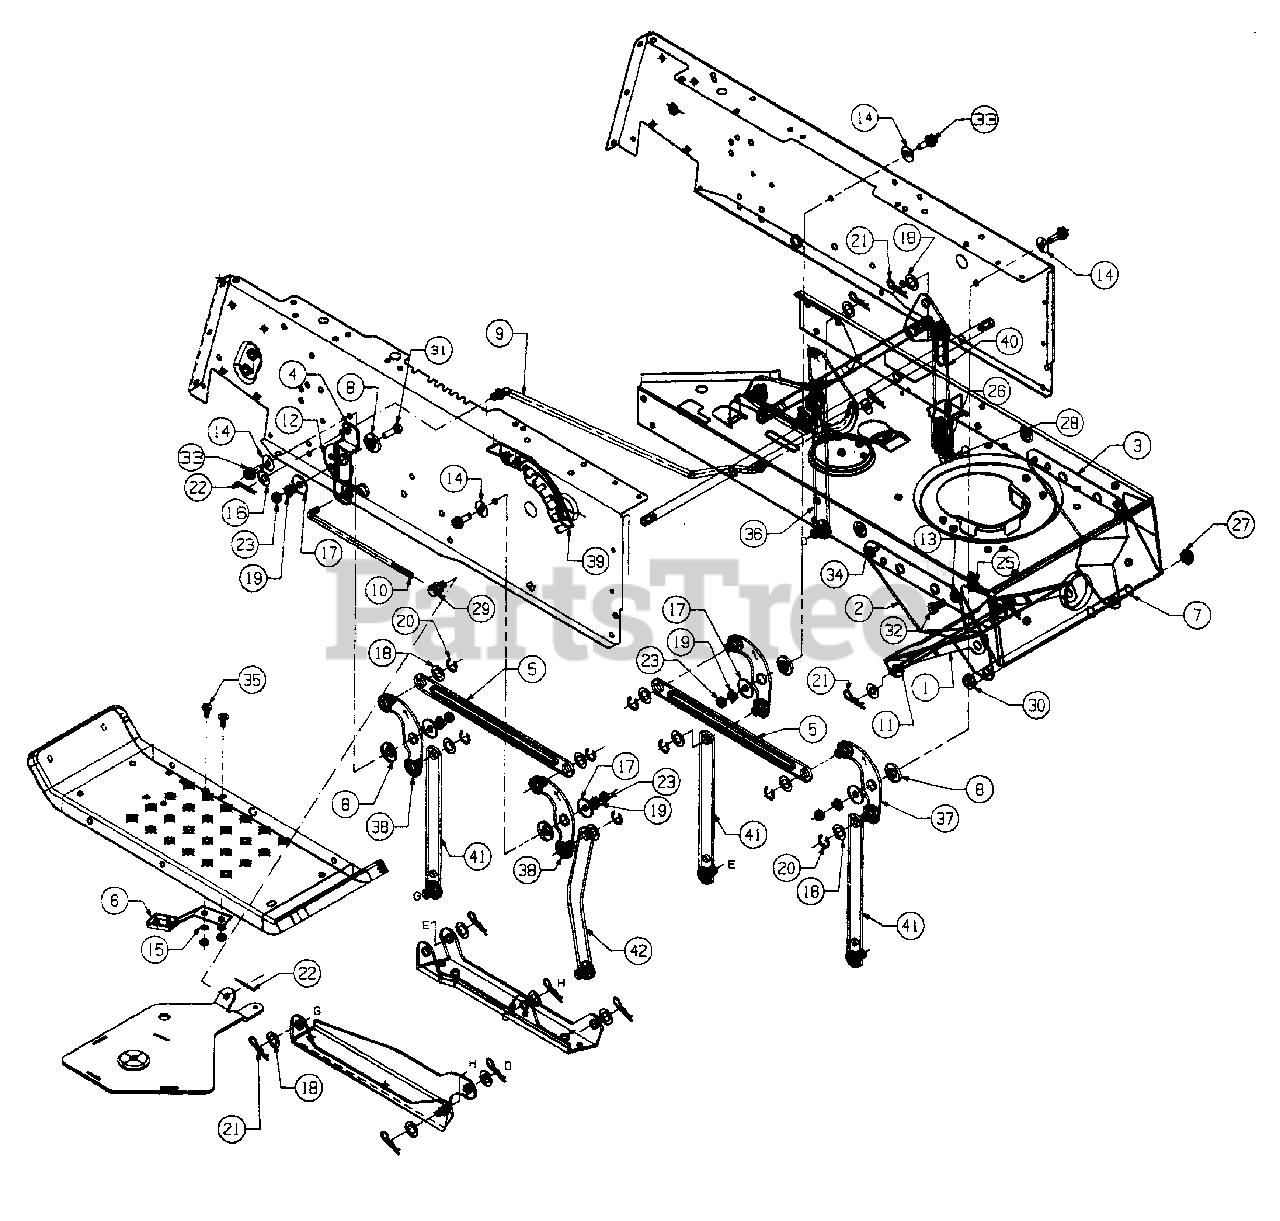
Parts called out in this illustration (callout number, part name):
1	Stabilizer Brkt.
2	Stabilizer Support Brkt.-R.H.
3	Stabilizer Support Brkt.-L.H.
4	Engagement Arm Link
7	Spacer .515" I.D. x 3.6" Lg.
8	Shld. Spacer
9	Deck Disengagement Rod
10	Deck Disengagement Rod
11	Shaft 3/8" Dia. x 9.34" Lg.
12	FL-Wash. .34" I.D. x 2.25" O.D.
13	L-Wash. 3/8" I.D.
14	Bell-Wash. .325" I.D. x .93" O.D.
15	L-Wash. 1/4" I.D.
16	FL. Wash. 3/8" I.D. x .87" O.D.
17	FL-Wash. .344" I.D. x 1-1/8" O.D.
18	FL-Wash. .531" I.D. x .93" O.D.
19	L-Wash. 5/16" I.D.
20	"E"-Ring
21	Hairpin Clip
22	Cotter Pin 1/8" Dia. x 1" Lg.
23	Hex Nut 5/16-18 Thd. (Gr. 5)
25	Hex Nut 3/8-24 Thd.
26	Hex Nut 1/2-20 Thd. (Gr. 5)
27	Hex Ins. Jam L-Nut 1/2-20 Thd.
28	Adjuster Life Link
29	Ferrule
30	Hex Bolt 1/2-20 x 11" Lg. (Gr. 5)
31	Hex Bolt 5/16-18 x 1" Lg. (Gr. 5)
32	Hex Bolt 3/8-24 x .75" Lg. (Gr. 5)
33	Hex Scr. 5/16-18 x .87" Lg.
34	Hex Wash. Hd. Scr. 5/16 x .5" Lg.
35	Carr. Bolt 1/4-20 x .62" Lg.
36	Deck Link Lift Ass'y.
37	Pivot Link Ass'y.-L.H.
38	Pivot Link Ass'y.-R.H.
39	Index Brkt.
41	Deck Link Hanger
